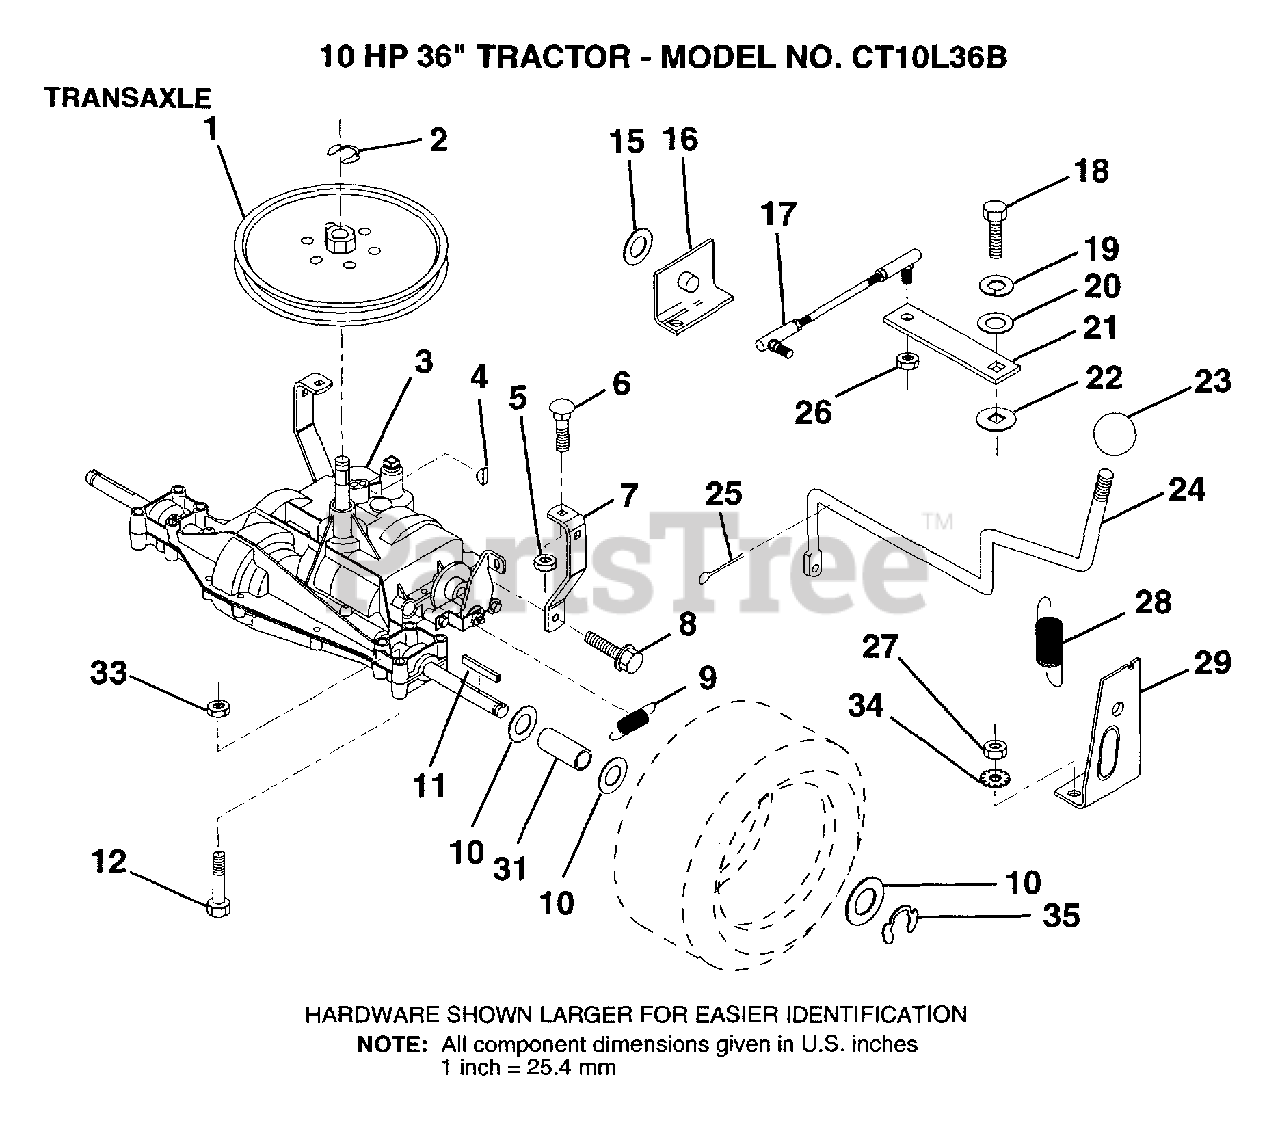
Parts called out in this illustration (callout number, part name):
1	PULLEY
6	BOLT
7	"STRAP,TORQUE"
8	SCREW
10	WASHER
11	SQUARE KEY
12	BOLT
16	"SUPT,HDLE SHT LH"
17	"LINK,SHIFT"
19	LOCKWASHER
20	WASHER LT
21	ARM SHIFT
22	WASH-SHFT PLT LT
23	KNOB T (1/2-HOLE)
24	"ROD,SHIFT"
25	PIN COTTER 1/8
26	NUT.LOCK.5/16-24
28	"SPRING,EXT"
29	"SUPT,HDLE RH"
31	SPACER
34	LOCKWASHER.5/16.E
35	E-RING LT
